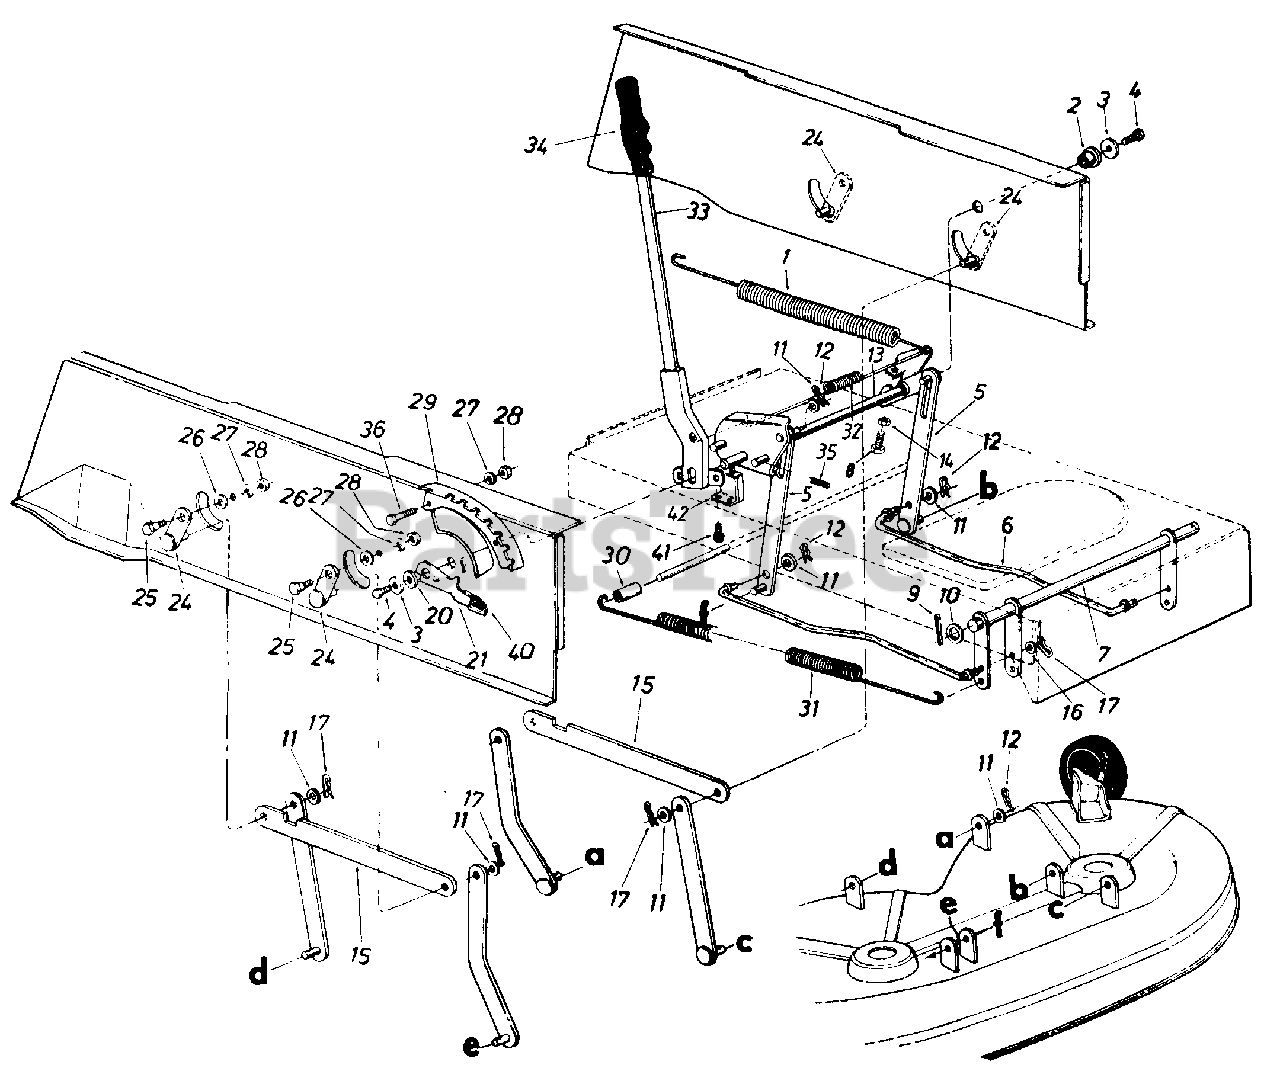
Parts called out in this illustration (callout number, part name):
1	Extension Spring .99" O.D. x 11.00" Lg.
2	Flange Bearing .634" l.D.
3	Fl-Wash. .344" I.D. x 1.125"
4	Hex Wash. Hd. 5/16-18 x .62" Lg.
5	Link Deck Lift Ass'y.
6	Stabilizer Rod
7	Stabilizer ShaR Ass'y.
8	Hex Tap Scr. 5/16-18 x 1" Lg.
9	Cotter Pin 1/8" Dia. x 1-1/4"
10	Fl-Wash. .635" l.D. x 1.12"
11	Fl-Wash. .531" l.D. x .940"
12	Inter. Cotter Pin
13	Lift Shaft Ass'y.
14	Hex Jam Nut 5/16-18 Thd.
15	Connecting Rod
16	Fl-Wash. .385" I.D. x .62"
17	Inter. Cotter Pin 1/2" Dia.
20	Flange Brg. .630" I.D.
21	Deck Lift-Down Stop
24	Pivot Link Ass'y.
25	Shld. Bolt .437" Dia. x .180 0 Lg. (5/1 6-1 8)
26	Fl-Wash. .344" l.D. x .62
27	L-Wash. 5/16" l.D.
28	Hex Nut 5/16-18 Thd.
29	Index Brkt.
30	Spacer .523" l.D. x 640" O.D. x 1.95" Lg.
31	Ext. Spring 13.25" Lg.
33	Lift Handle Ass'y.
34	Grip
35	Intern. Cotter Pin 1/2" Dia.
36	Hex 801t 5/16-18 x .75"
41	Hex AB-Tap Scr. #10 x .50"
42	Safety Switch
